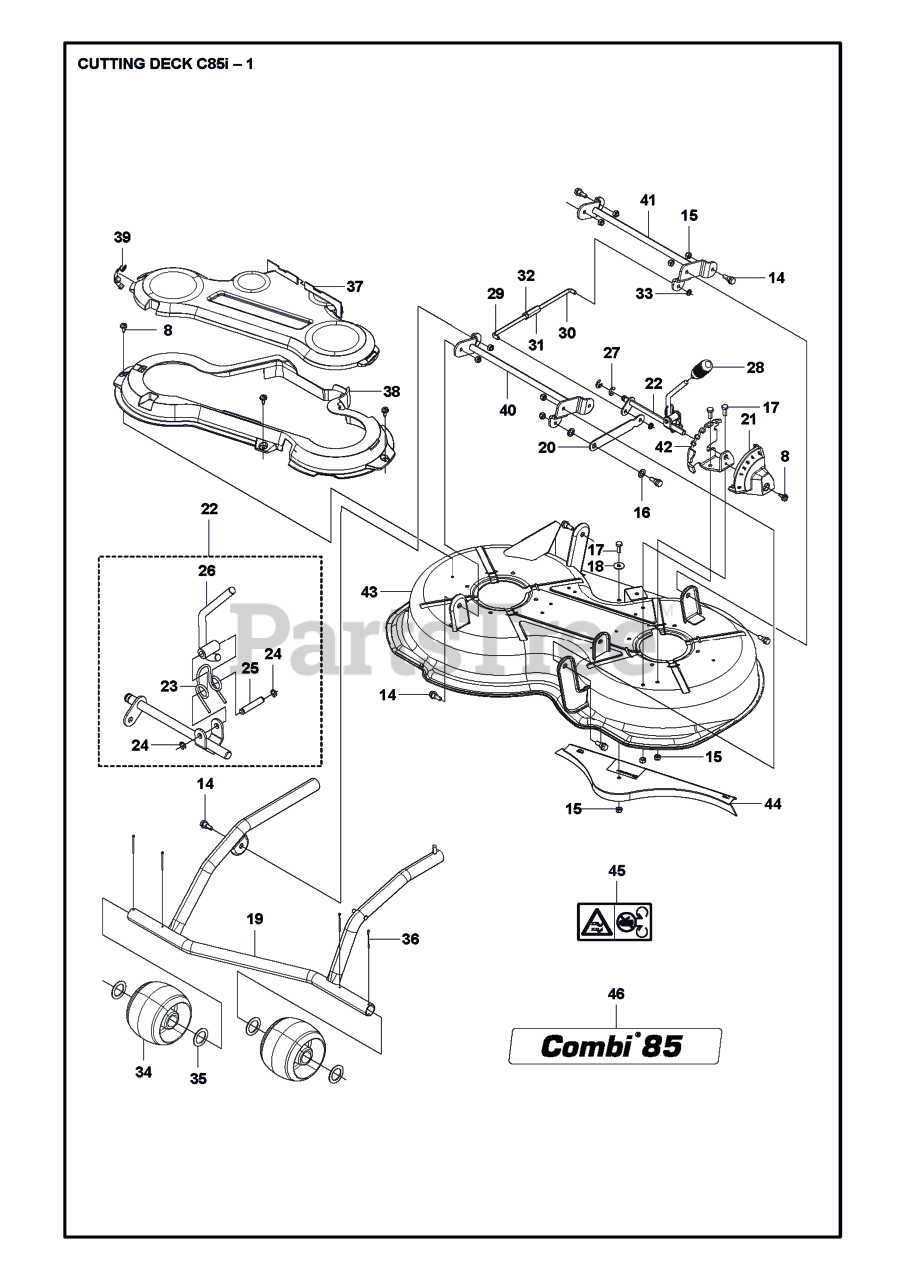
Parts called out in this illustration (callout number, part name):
15	LOCKNUT M8
18	WASHER - 25X8.5X2.3
27	RETAINING RING
32	NUT
36	COTTER PIN
